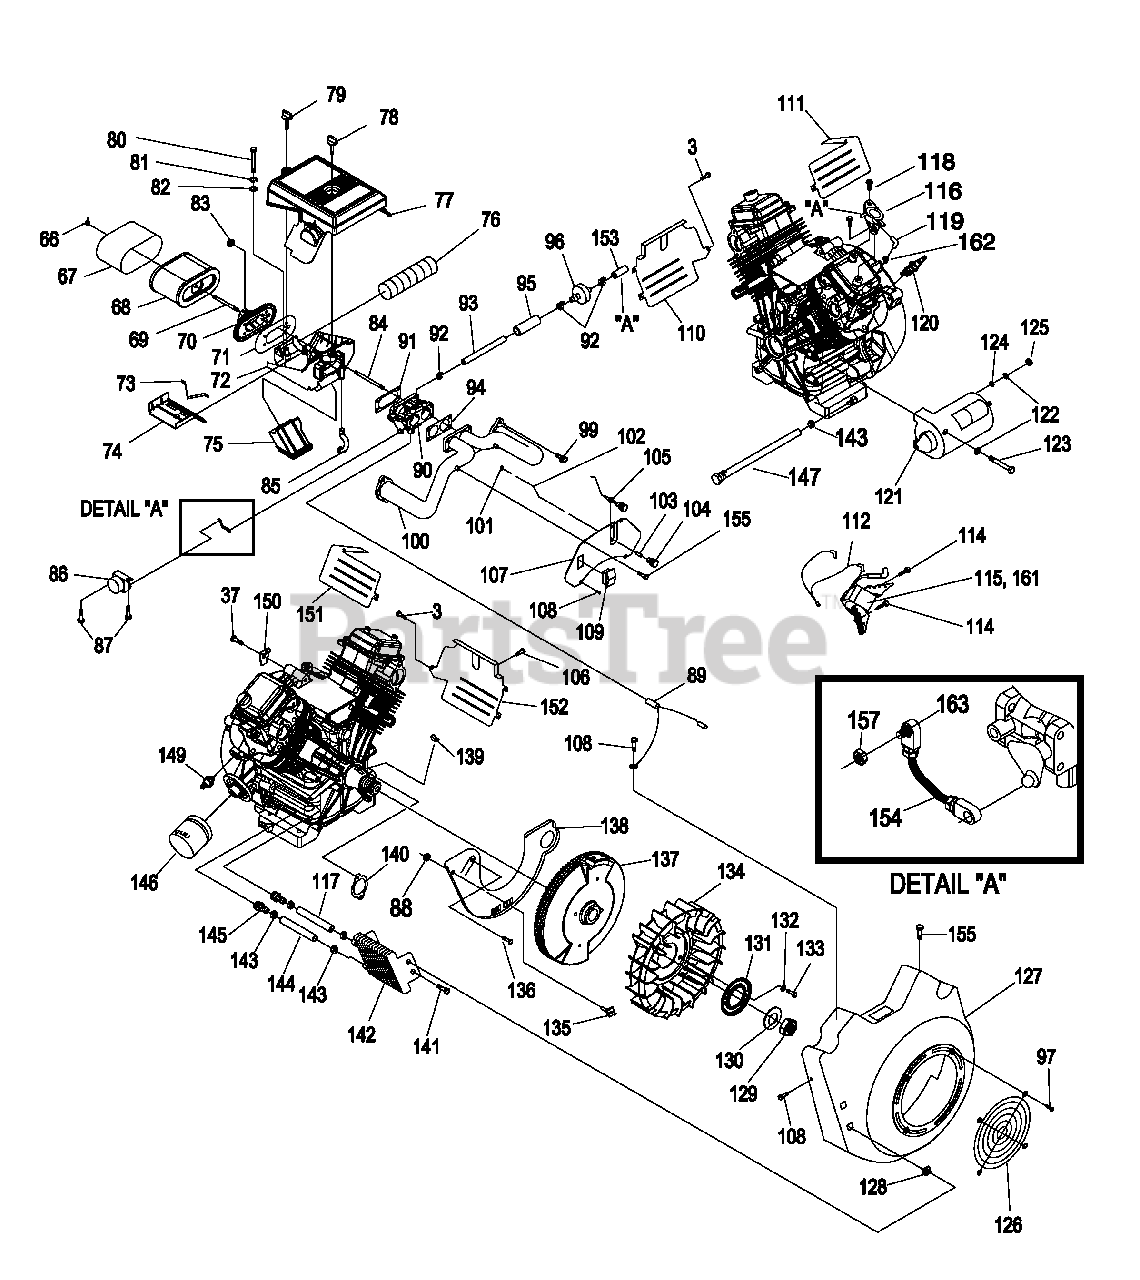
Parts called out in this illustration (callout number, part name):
66	WINGNUT, AIRBOX
67	PRECLEANER, AIR
68	ELEMENT, AIR CLEANER
69	STUD M6-1.0 X 73
70	ADAPTOR, SPIT BACK
71	GASKET, SPITBACK
72	BASE, AIRBOX
73	SPRING, WINTER/SUMMER VALVE
74	VALVE, SUMMER / WINTER
75	SNORKEL, AIR INTAKE
76	TUBE, HEAT RISER 50.8 I.D.
77	COVER, AIRBOX
78	KNOB, AIRBOX 17mm
79	KNOB, AIRBOX 95MM
80	SCREW HHC M6-1.0 X 35
81	WASHER LOCK M6-1/4
82	WASHER FLAT 1/4
83	NUT, HEX FLANGE WHIZ M6-1.0
84	STUD, METRIC
85	HOSE, BREATHER
86	CONTROLLER ASSEMBLY
87	SCREW HHTT M5-0.8 X 10
88	NUT, HEX LOCK M5-0.8 ZINC
89	ASSEMBLY, WIRE
90	CARBURETOR, H990 W/BALL STUD
91	GASKET, CARB TO SPACER (GT-990)
92	CLAMP HOSE BAND 1/4
93	HOSE1/4 ID SAE 30R7 SETIFLEX II 9" PRE-CUT
94	GASKET, MANIFOLD TO CARBURETOR
95	SLEEVING, FLEXO HW 3/4 3"
96	FILTER, FUEL
97	SCREW, HHTT M6-1 x 10 LONG
98	NUT, HEX LOCK M5-0.8 ZINC
99	SCREW, SHC M8-1.25 x 30LG SEMS
100	MANIFOLD, INTAKE
101	NUT HEX M3-0.5
102	ROD, SUMMER / WINTER VALVE
103	BUSHING, MINI CONTROL PANEL
104	KNOB, CONTROL SUMMER / WINTER
105	CHOKE ASSEMBLY
106	SCREW TAPTITE M5-0.8 X 8 ZP
107	PANEL, CONTROL FACE PLATE
108	SCREW TAPTITE M6-1.0X 12 CLEAR ZINC
109	SWITCH ROCKER
110	WRAPPER, LOWER CYLINDER 2
111	WRAPPER, UPPER CYLINDER 2
112	ASSEMBLY, GROUND WIRE
114	SCREW TAPTITE M6-1.0 X 20 ZINC
115	ASSY, IGN COIL W/DIODE NO ADV
116	PUMP, IMPULSE
117	HOSE, 3/8" ID x 6-1/2" SAE J30R9
118	SCREW, HHFCS M6-1.0 X 16 G8.8
119	ELBOW, RUBBER 90 DEG. GASOLINE
120	SPARKPLUG, CHAMPION RC14YC
121	STARTER MOTOR GEAR REDUCED
122	WASHER LOCK M8-5/16
123	SCREW HHC M8-1.25 X 85 G8.8
124	WASHER, FLAT M8
125	NUT, HEX M8-1.25 YELLOW ZINC
126	GUARD,FAN
127	HOUSING, BLOWER GAS COOLER
128	NUT, GROMMET 1/4 PLUG
129	NUT,HEX M24
130	WASHER, M24
131	PLATE, FAN
132	WASHER SHAKEPROOF INT M8 SS
133	SCREW HHC M8-1.25 X 12 G8.8
134	FAN, NYLON
135	ASSY,GROUND WIRE CONNECTOR
136	SCREW TAPTITE M6-1X10 YELLOW CHROME
137	FLYWHEEL ASSEMBLY
138	PLATE, BACKING GT990 W/OIL COOL ZINC
139	KEY, WOODRFF 4 X 19D
140	GASKET, MANIFOLD / PORT
141	PLASTITE,1/4-15 X 3/4
142	COOLER, OIL
143	CLAMP, HOSE OETIKER STEPLESS 17mm
144	HOSE, 3/8" I.D. X 6" SAE J30R9
145	BARBED STR 1/4NPT X 3/8
146	OIL FILTER, 90mm w/LOGO
147	ASSEMBLY, OIL DRAIN HOSE
149	SWITCH, OIL PRESS
150	BRACKET, AIRBOX SUPPORT
151	WRAPPER, UPPER CYLINDER 1
152	WRAPPER, LOWER CYLINDER 1
153	HOSE,1/4" SAE 30R7 SETIFLEX II
154	ASSY, ROD, GOV. STEPPER MOTOR
155	SCREW HHHC M6-1.0 X12
157	NUT, LOCK HEX M3-0.5 (GT-990)
160	SCREW HHFC M6-1.0 X 10mm
161	ASSY, IGN COIL W/DIODE NO ADV
162	CLAMP, HOSE BAND GREEN
163	BALL STUD, 10mm
